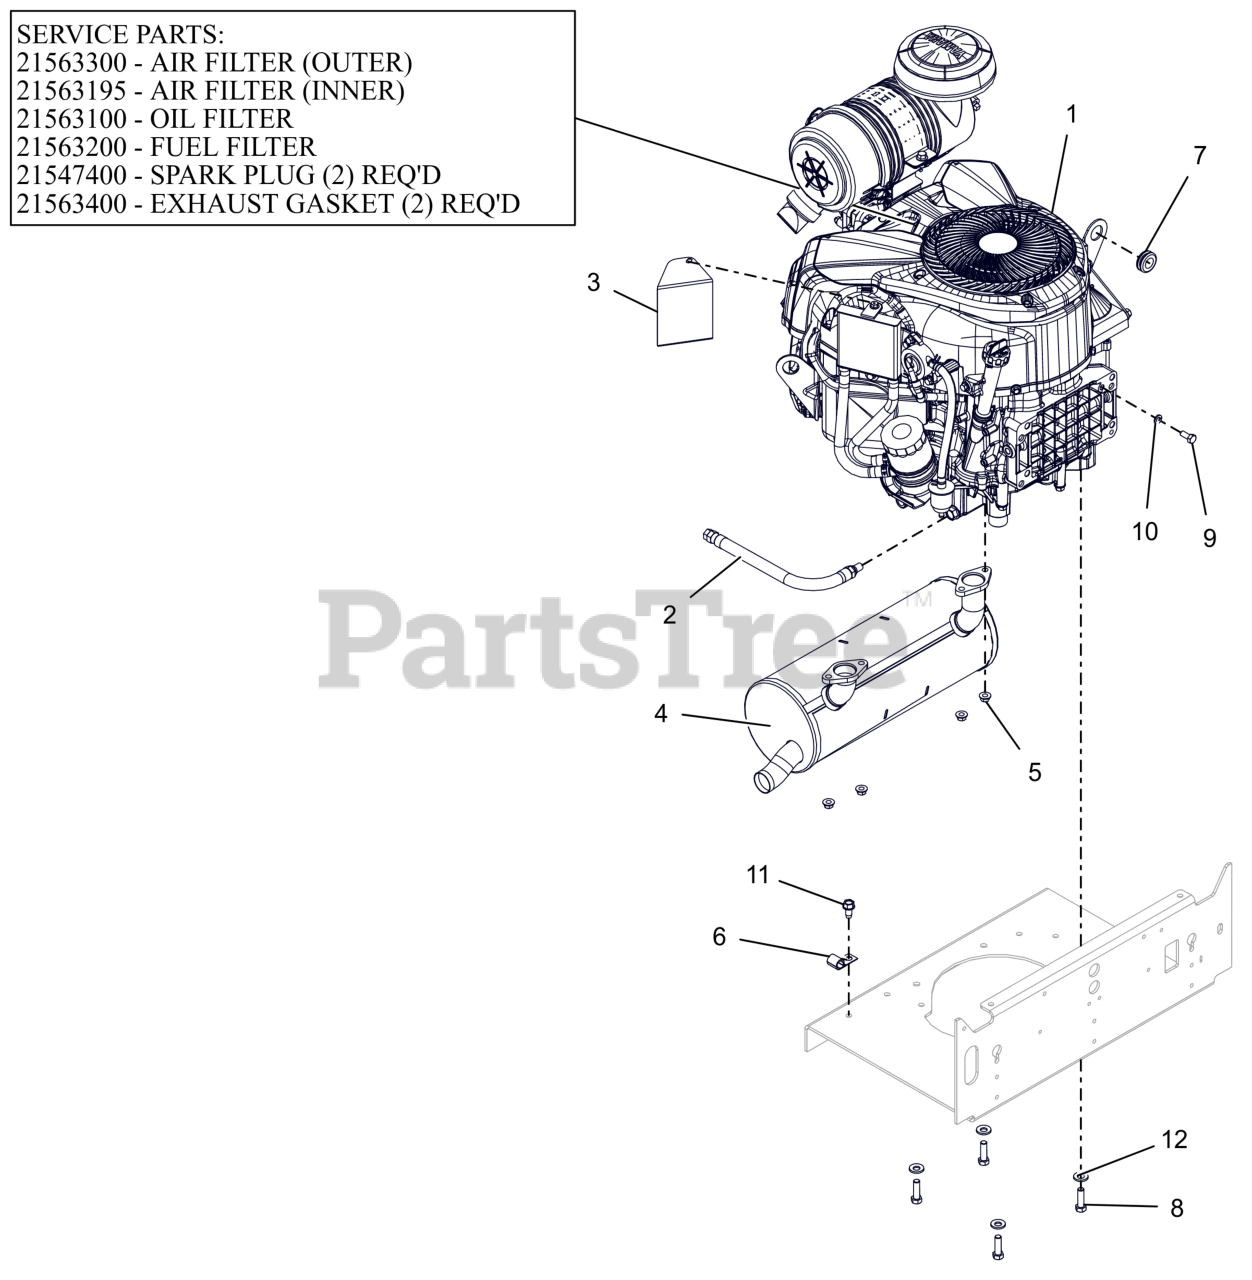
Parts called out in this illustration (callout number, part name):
1	ENGINE, YAMAHA MX800V
2	HOSE, OIL DRAIN
3	DEFLECTOR,YAMAH OIL COOLER AIR
4	MUFFLER, YAMAHA
5	NUT-LK-TOP-FLG M8 ZCC
7	GROMMET,RUBBER.688 IDX1.000 OD
8	BLT, HEX .38-16X1.25 G5 ZCC NT
9	BLT,HEX .31-18X.75 G5 ZCC
10	WSHR,LK-REG .312X.078 ZCC
11	SCR,TAP .375-16X.75 HWH TR ZCC
12	WASHER, 3/8" SPRING DISC
